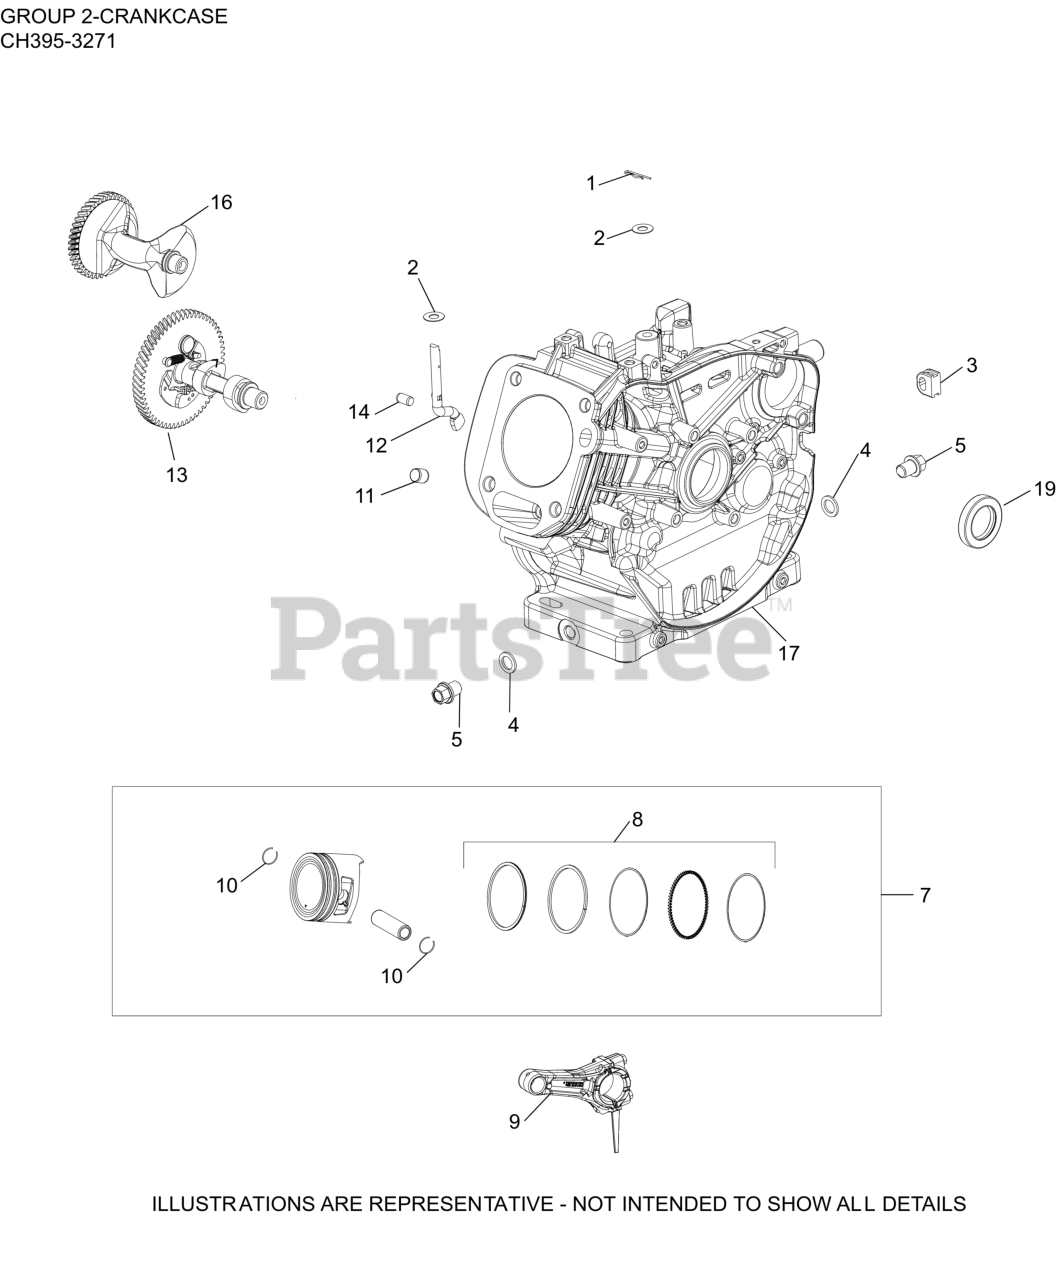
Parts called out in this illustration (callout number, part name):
1	CLIP, GOVERNOR SHAFT
2	WASHER, FLAT
3	GROMMET, CRANKCASE
4	WASHER, DRAIN PLUG
5	KIT, DRAIN PLUG
7	KIT, PISTON AND RINGS
8	RING SET- USE 17 874 06-S
8	RING, SET PISTION (std)
9	ROD, CONNECTING ASSEMBLY
10	RETAINER, PISTON PIN
11	PIN, DOWEL CYLINDER HEAD
12	SHAFT, GOVERNOR CROSS
13	CAMSHAFT ASSEMBLY
14	PIN, DOWEL
16	SHAFT, BALANCE
17	CRANKCASE
19	SEAL, RADIAL SHAFT
